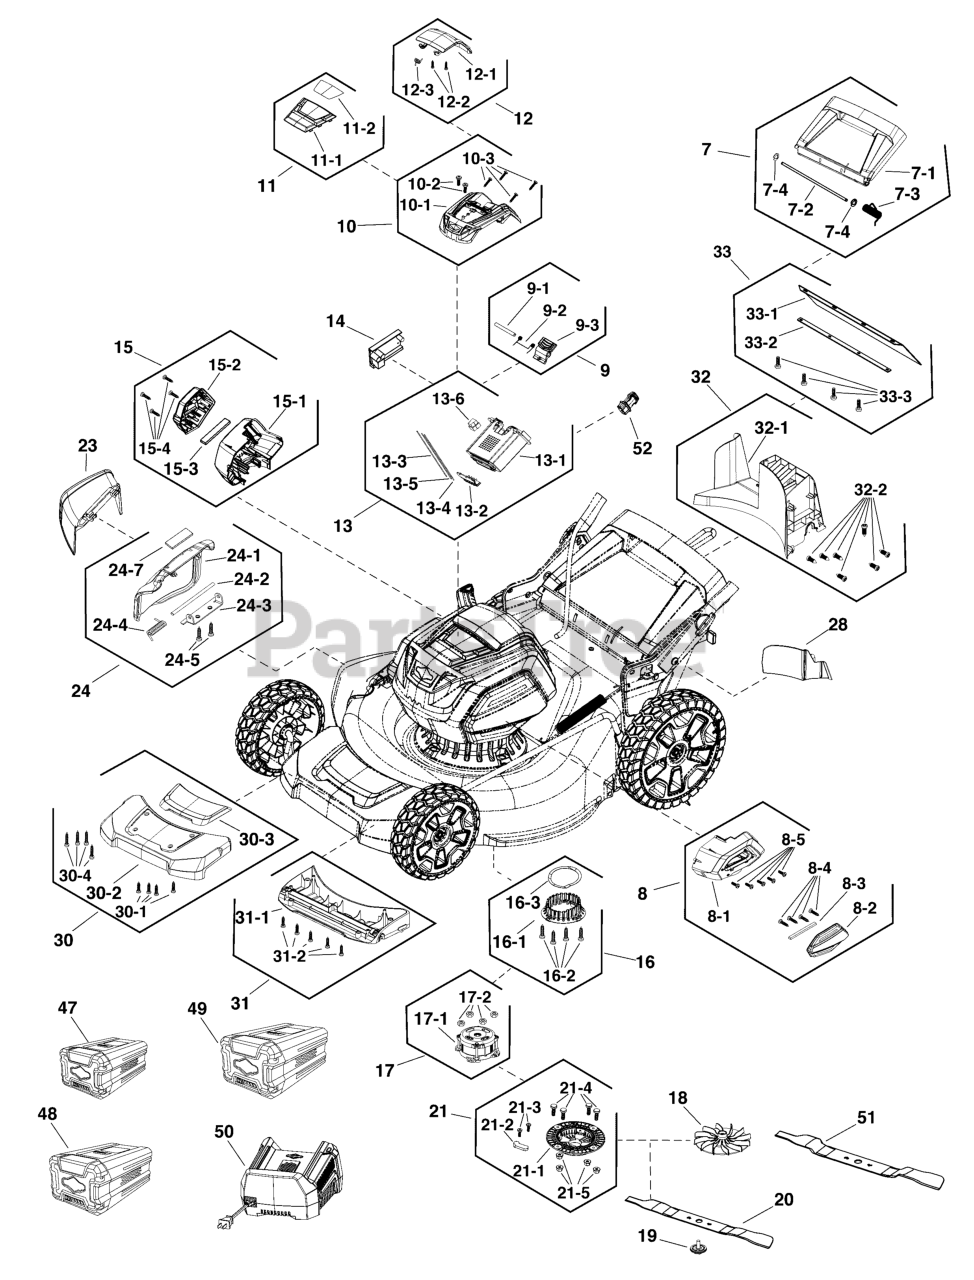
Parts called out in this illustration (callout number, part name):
7	KIT, Rear Cover
7-1	COVER, Rear
7-2	PIN
7-3	SPRING
7-4	WASHER, Split
8	KIT, Left Cover
8-1	COVER, Left
8-2	HOUSING, Left
8-3	SCREEN, Dust
9	KIT, Battery Release
9-1	PIN
9-2	SPRING
9-3	BUTTON
10	KIT, Battery Cover
10-1	COVER, Top
11	KIT, Cover
11-1	TOP COVER
11-2	SHROUD
12	KIT, Top Cover
12-1	BAFFLE, Front
12-1	COVER, Battery
12-3	SPRING
13	KIT, Battery Compartment
13-1	HOUSING, Battery
13-2	TERMINAL
13-3	WIRE, Red
13-4	WIRE, Yellow
13-5	WIRE, Black
13-6	CONNECTOR
14	KIT, PCB, NA
15	KIT, Cover, Right
15-1	COVER, Right
15-2	COVER, Right
15-3	SCREEN, Dust
16	KIT, BASE
16-1	BASE
16-3	SEAL
17	MOTOR ASSEMBLY
17-1	MOTOR
17-2	NUT
18	KIT, Fan
19	KIT, Bolt
20	KIT, Blade
21	KIT, Motor Base
21-1	MOTOR BASE
21-2	DISC, Tension
21-4	BOLT
21-5	NUT
23	KIT, Deflector
24	KIT, Cover, Side Discharge
24-1	SIDE DISCHARGE COVER
24-2	PIN
24-3	BRACKET
24-4	SPRING, Torsion
24-5	BOLT
24-7	LABEL
28	MULCH PLUG
30	KIT, Front Panel
30-2	BUMPER
30-3	COVER, Bumper
31	KIT, Front Bulkhead
31-1	BAFFLE, Front
32	BAFFLE, Rear
32-1	BULKHEAD, Back
33	KIT, Rear Deflector
33-1	FLAP, Rear
33-2	BRACE
47	* BATTERY, 2.0, 82V NA
48	* BATTERY, 4.0, 82V NA
49	* BATTERY, 5.0, 82V NA
50	* CHARGER, Battery, NA
51	BLADE, Mulching, 19"
52	KEY, Safety
